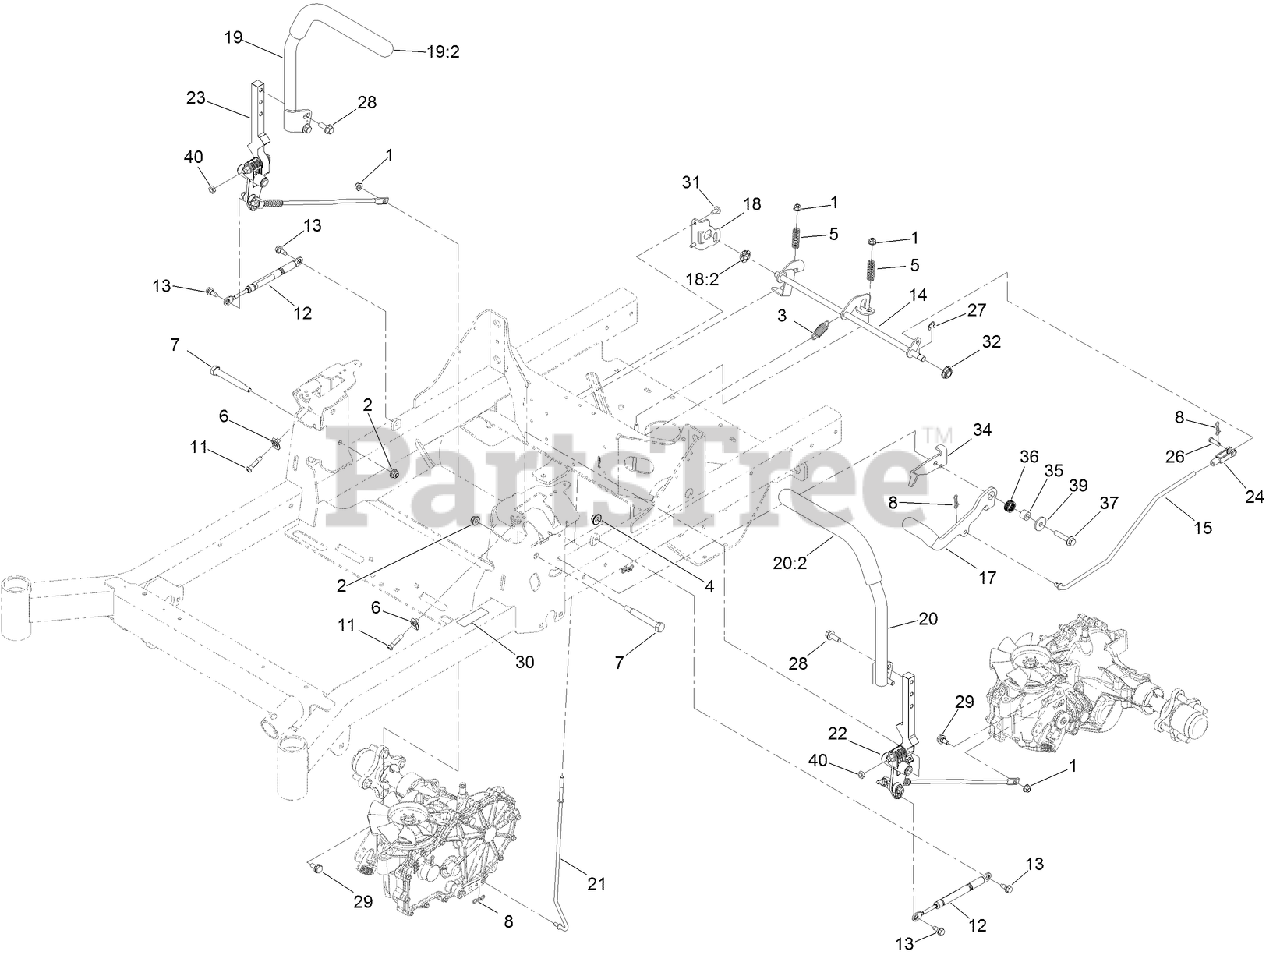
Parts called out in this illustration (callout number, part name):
1	NUT-HF, NI
2	NUT-HF, NI
3	SPRING-EXTENSION
4	NUT-FLANGE, NI
5	SPRING-COMPRESSION
7	BOLT-PIVOT
8	PIN-COTTER, LOCKING
11	SCREW-HSBH
12	DAMPER
13	SCREW-SHOULDER
14	SHAFT-BRAKE
15	LINKAGE-BRAKE, UPPER
17	LEVER-BRAKE (WITH GRIP)
18	BRACKET-BRAKE
18:2	BEARING-SPHERICAL
19	RH EXTENDED CONTROL HANDLE ASM
20	LH EXTENDED CONTROL HANDLE ASM
21	LINKAGE-BRAKE, LOWER
22	LH MOTION CONTROL ASM
23	RH MOTION CONTROL ASM
24	YOKE-ADJUSTABLE
26	PIN-CLEVIS
27	RING-RETAINING, EXTERNAL
28	SCREW-HHF
29	BOLT-SHOULDER,HFH
30	DECAL-BRAKE INTL
31	SCREW-TORX
32	BEARING-SPHERICAL
34	BRACKET-BRAKE
35	BUSHING
36	SPRING-WAVE
37	SCREW-HHF
39	WASHER
40	NUT-JAM
